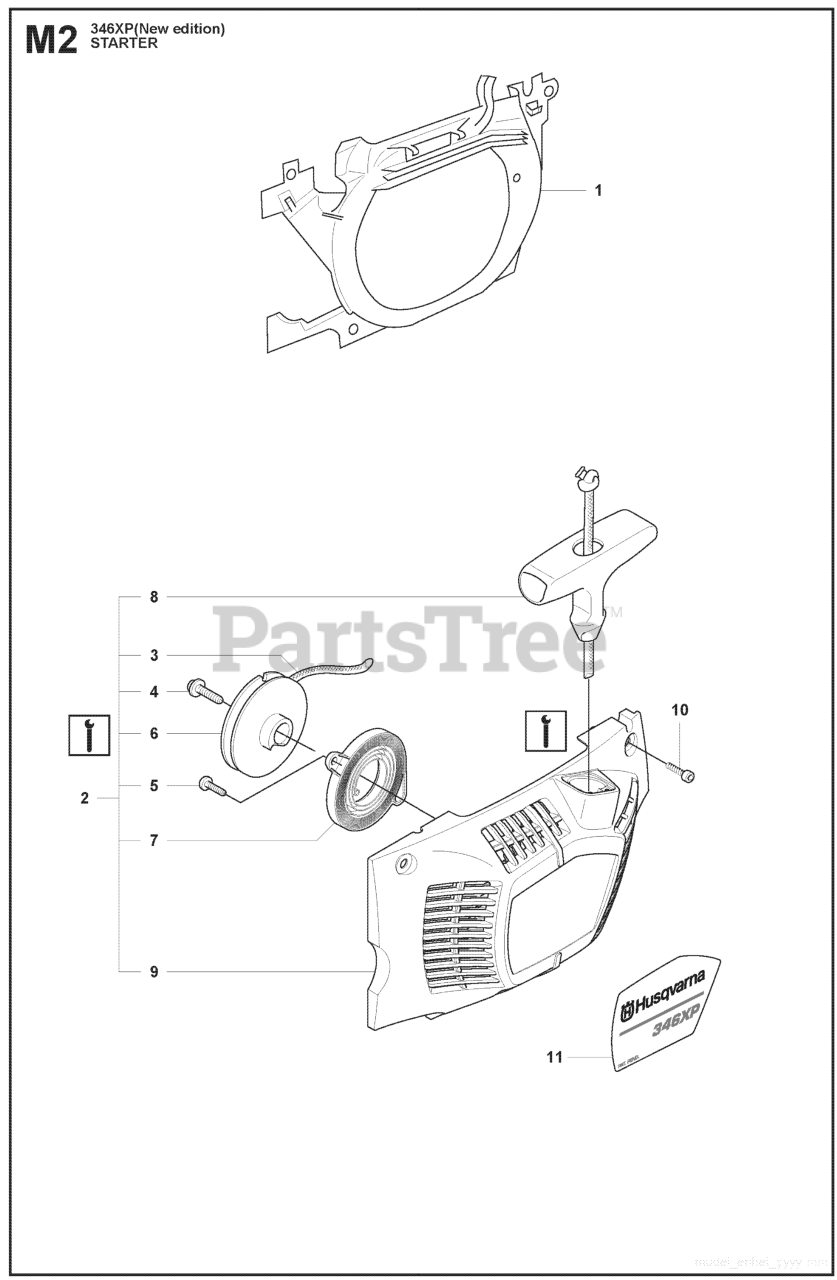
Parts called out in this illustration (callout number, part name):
1	AIR CONDUCTOR
3	STARTER ROPE
6	PULLEY
7	RETURN SPRING
9	STARTER HOUSING
10	SCREW.CIHPANMO M5X19 10.9
11	LABEL
